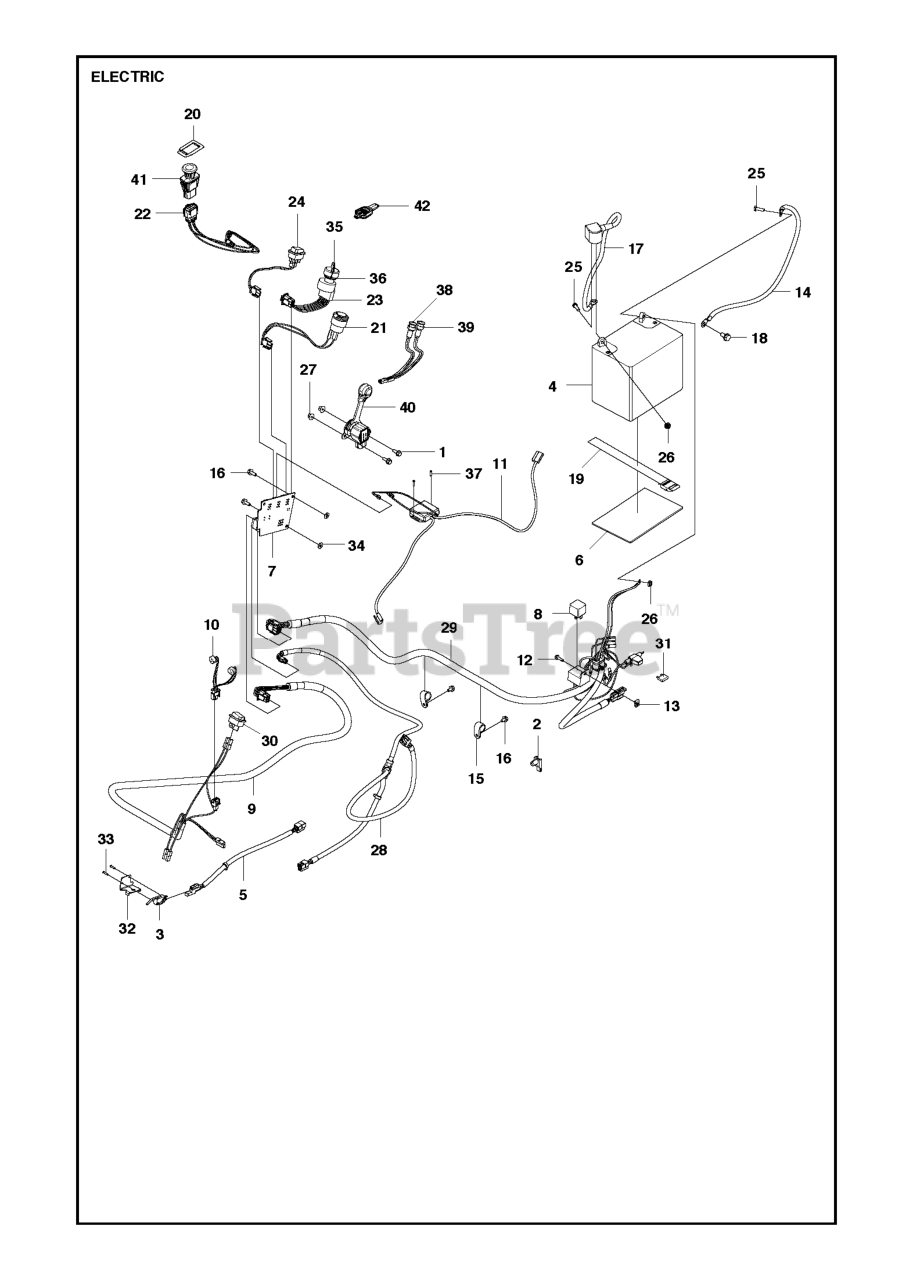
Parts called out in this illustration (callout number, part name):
1	Screw
3	MICRO SWITCH
5	WIRING
25	SCREW EHHM
27	NUT FLANGE
31	FUSE 20AMP
41	SWITCH.PTO.10AMP.SEALED.6P.SPS
